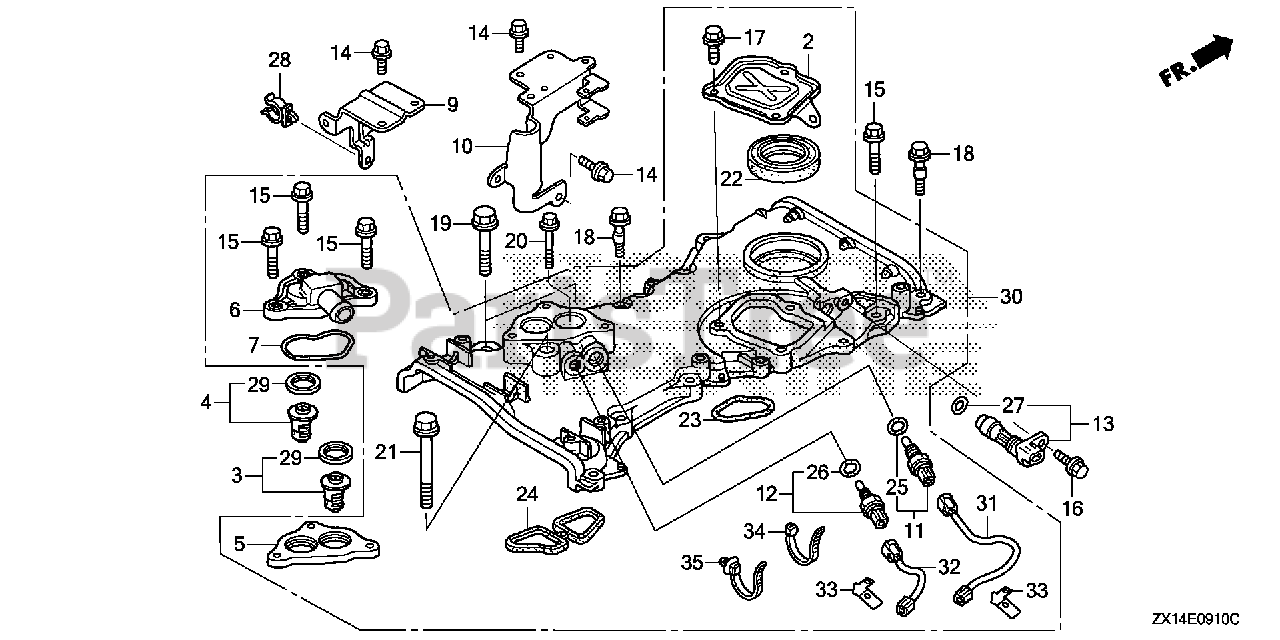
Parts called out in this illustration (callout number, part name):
2	COVER, CHAIN CASE
3	THERMOSTAT ASSY.
4	THERMOSTAT ASSY.
5	SPACER KIT, THERMOSTAT COVER
5	SPACER, THERMOSTAT COVER *TGRAY* (GRAY)
6	COVER, THERMOSTAT
7	GASKET, THERMOSTAT COVER
9	BRACKET B, HARNESS CLIP
10	BRACKET C, HARNESS CLIP
11	SENSOR ASSY., WATER TEMPERATURE
12	SENSOR ASSY., WATER TEMPERATURE
13	SENSOR ASSY., CRANK
14	BOLT, FLANGE (6X14) (CT200)
15	BOLT, FLANGE (6X28)
16	BOLT, FLANGE (6X16)
17	BOLT, FLANGE (6X14)
18	BOLT, SPECIAL (6X31)
19	BOLT, FLANGE (10X43)
20	BOLT, FLANGE (6X38)
21	BOLT, FLANGE (10X70)
22	OIL SEAL (43X58X7) (ARAI)
23	O-RING, CHAIN CASE
24	GASKET, CHAIN CASE
25	O-RING (9.5X1.5) (HONDA KIKAKI)
26	O-RING (9.5X1.9)
27	O-RING (15X1.9)
28	CLAMP (18.5MM)
29	RUBBER, RING
30	CASE KIT, CHAIN
31	SUB-WIRE HARNESS ASSY. (A)
32	SUB-WIRE HARNESS ASSY. (B)
33	BRACKET, SUB-HARNESS CLIP
34	BAND, WIRE HARNESS
35	CLIP, HARNESS BAND (145MM) (BLACK)
